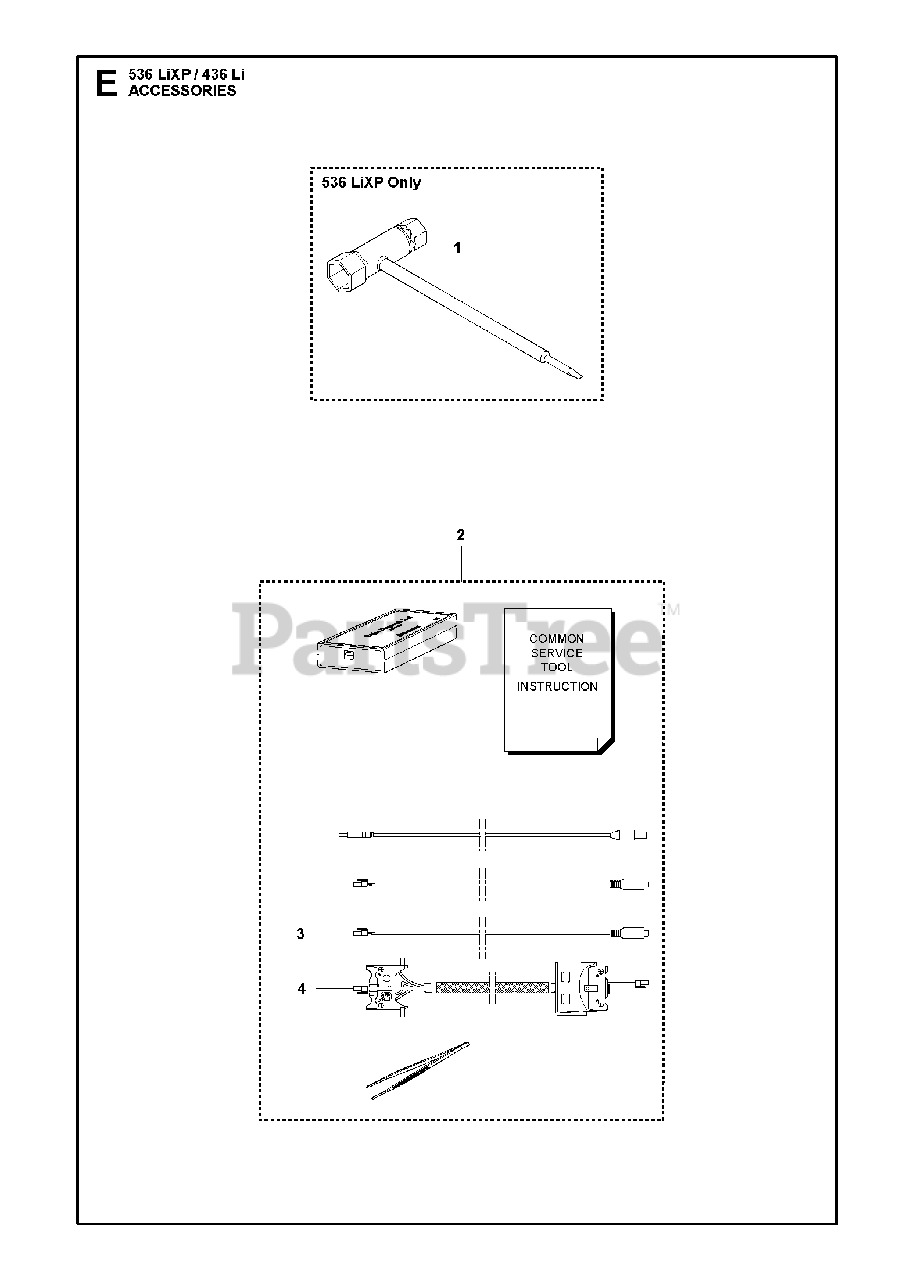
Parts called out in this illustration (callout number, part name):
1	COMBI TOOL
2	DIAGNOSTIC TOOL KIT
3	CABLE ASSY
4	WIRING ASSY
